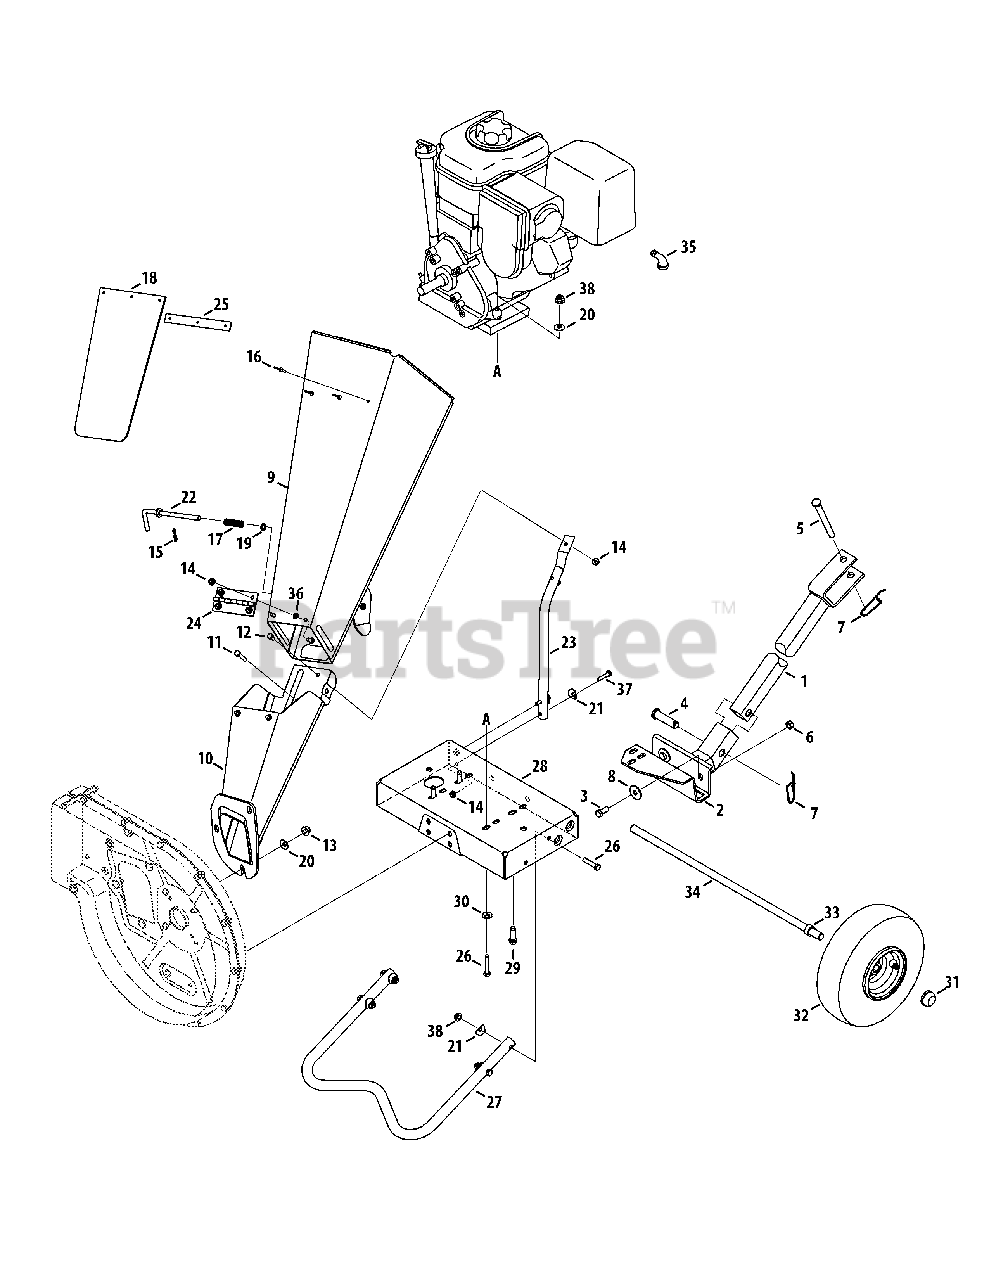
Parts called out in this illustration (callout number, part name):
1	Tongue Hitch Mount
2	Base Hitch Mount
3	Hex Cap Screw, 3/8-16 x.88
4	Clevis Pin,.625 x 2.4
5	Clevis Pin,.50 x 4.62
6	Flange Lock Nut, 3/8-16
7	Spring Pin
8	Flat Washer,.411 x 1.25 x 1.0
9	Upper Chipper Chute Assembly
10	Lower Chipper Chute Assembly
11	Hex Cap Screw, 1/4-20 x 1.25
12	Screw, 1/4-20 x .50
13	Hex Nut, 5/16-18
14	Flange Lock Nut 1/4-20
15	Cotter Pin
16	Pop Rivet
17	Compression Spring,.531 x 1.75
18	Chute Flap
19	Flat Washer
20	Bell Washer.340 ID x.872 OD
21	Washer,.320 ID x.93 OD
23	Chipper Chute Support
24	Chipper Chute Hinge
25	Chute Flap Strip
26	Hex Cap Screw, 5/16-18 x 1.50
28	Frame Assembly
29	Hex Sems Screw, 3/8-16 x 1.25
30	Special Lock Washer, 5/16
31	Push Cap, 5/8
32	Wheel, 10 x 4 x 4
32	Flange Bearing
32	Flange Bearing w/fitting
33	Spacer, .64 x .88 x .38
34	Axle, 22.47"
35	Elbow Fitting
36	Push Nut,.25ID x.50OD
37	Hex Cap Screw, 1/4-20 x 1.250
38	Flange Lock Nut, 5/16-18
